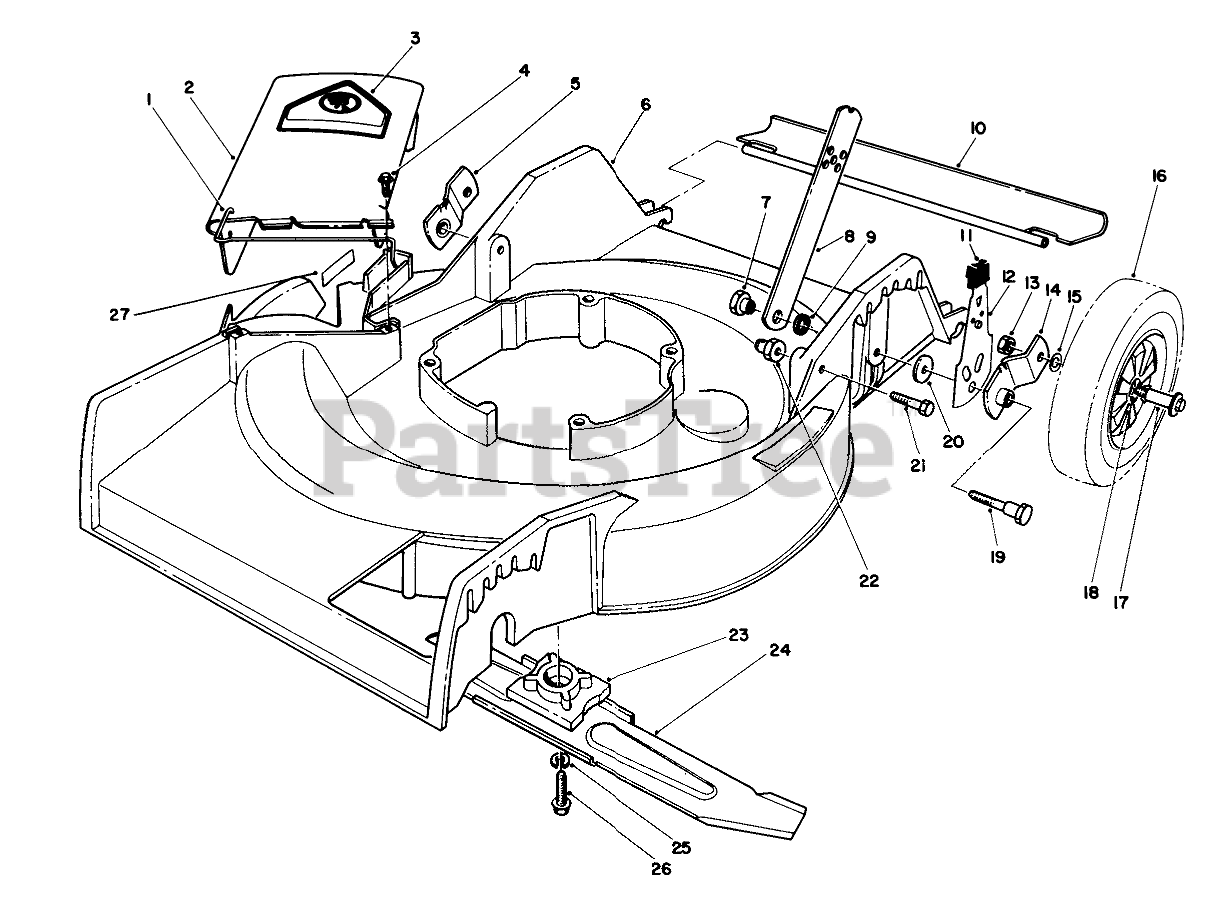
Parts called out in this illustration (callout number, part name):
1	SPRING HINGE
2	Deflector (Incl. Ref. #1 & 3)
3	DECAL-DANGER
4	SCREW-HWH
5	Pivot Arm
6	Housing-21" (Incl. Ref. #27)
7	HANDLE PIVOT NUT
8	HANDLE LATCH
9	SPACER
10	SHIELD - TRAILING
11	KNOB-ARM
12	REAR SPRING ARM ASM
13	Nut
14	Pivot Arm
15	WASHER
16	Wheel & Tire Assembly (Incl. Ref. #18)
17	BOLT-WHEEL
18	BUSHING
19	PIVOT SCREW
20	PIVOT WASHER
21	SCREW-HH
22	HANDLE PIVOT NUT
23	BLADE RETAINER
24	Blade
25	WASHER-LOCK
26	SCREW-HH
27	DANGER DECAL
